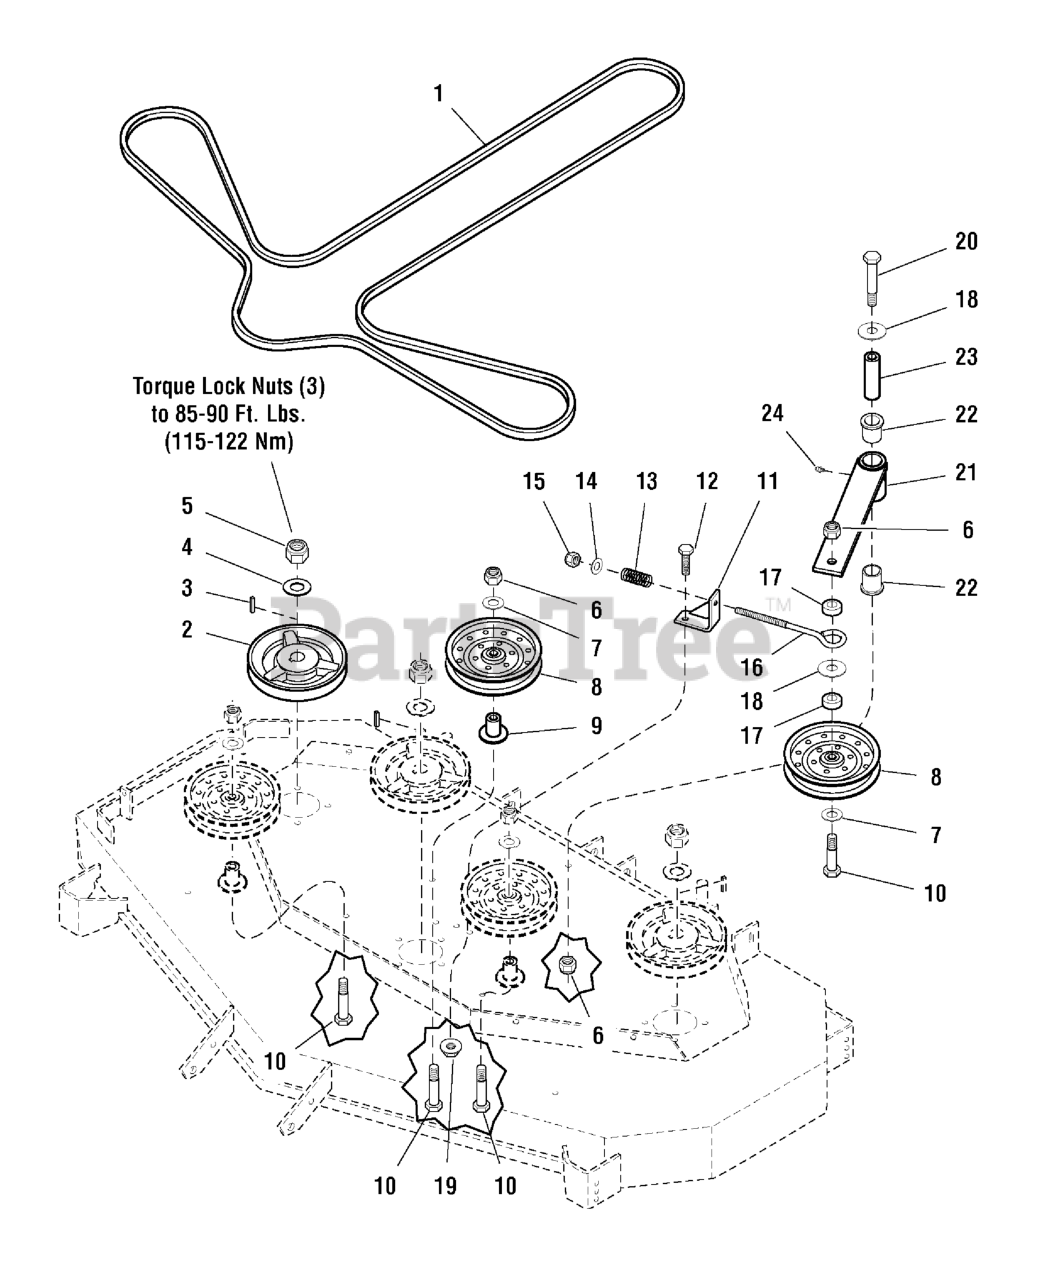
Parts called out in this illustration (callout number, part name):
1	BELT, 5V, 175.90EL, LG ARAMID, WRPD, RC
2	SPINDLE PULLEY
3	KEY, 1/4 SQ. X 1-1/4
4	WASHER, Spring
5	NUT, 5/8-18 Hex Nylon Lock
6	NUT, 1/2-13 HEX NYLON LOCK
7	WASHER, 1/2 SAE
9	IDLER MOUNT
10	BOLT, 1/2-13 X 3" GD5 CZ
11	SPRING ANCHOR
12	BOLT, 3/8-16 X 1" GD5 CZ
13	SPRING, Compression
14	WASHER, 3/8 SAE
15	NUT, 3/8-16 HEX NYLON LOCK
16	EYEBOLT, 3/8" x 8"
17	SPACER, .52 x 1.00 x .44
18	WASHER, 1/2" USS
19	NUT, 3/8-16 Hex Serrated Flange
20	BOLT, 1/2-13 x 4-1/2
21	IDLER ARM
22	BUSHING, FLANGE
23	SPACER, .52 x 1.00 x 3.50
24	GREASE FITTING
